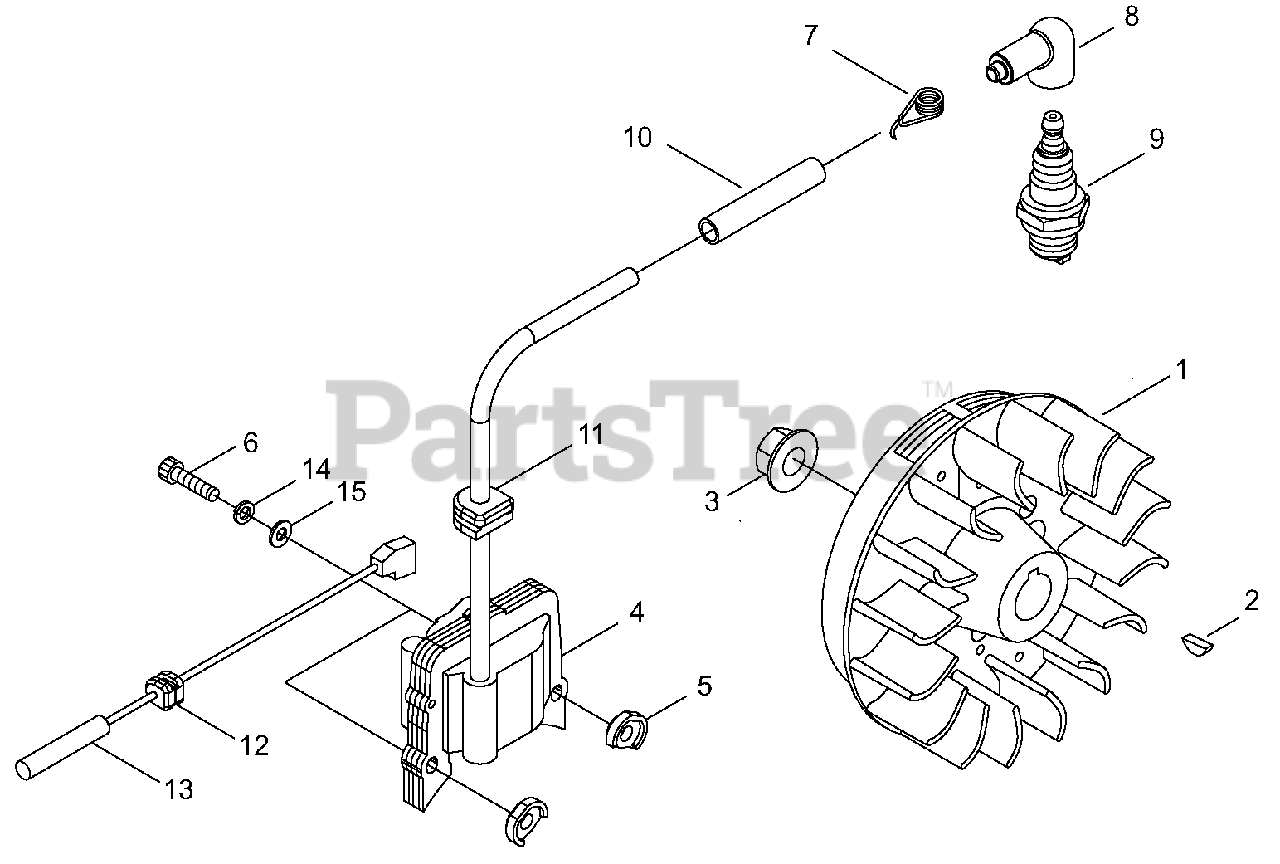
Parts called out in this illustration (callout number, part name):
1	FLYWHEEL
2	KEY, WOODRUFF 3×10
3	NUT, FLANGE M10
4	COIL, IGNITION
5	LEAD - IGNITION
6	TUBE, INSULATOR
7	GROMMET
8	GROMMET, LEAD
9	CAP, SPARK PLUG
10	TERMINAL, SPARK PLUG
11	COLLAR 4
12	BOLT M4×24
13	WASHER, SPRING 4 MM
14	WASHER 4.3×9.6×0.8
15	SPARK PLUG - CJ8
